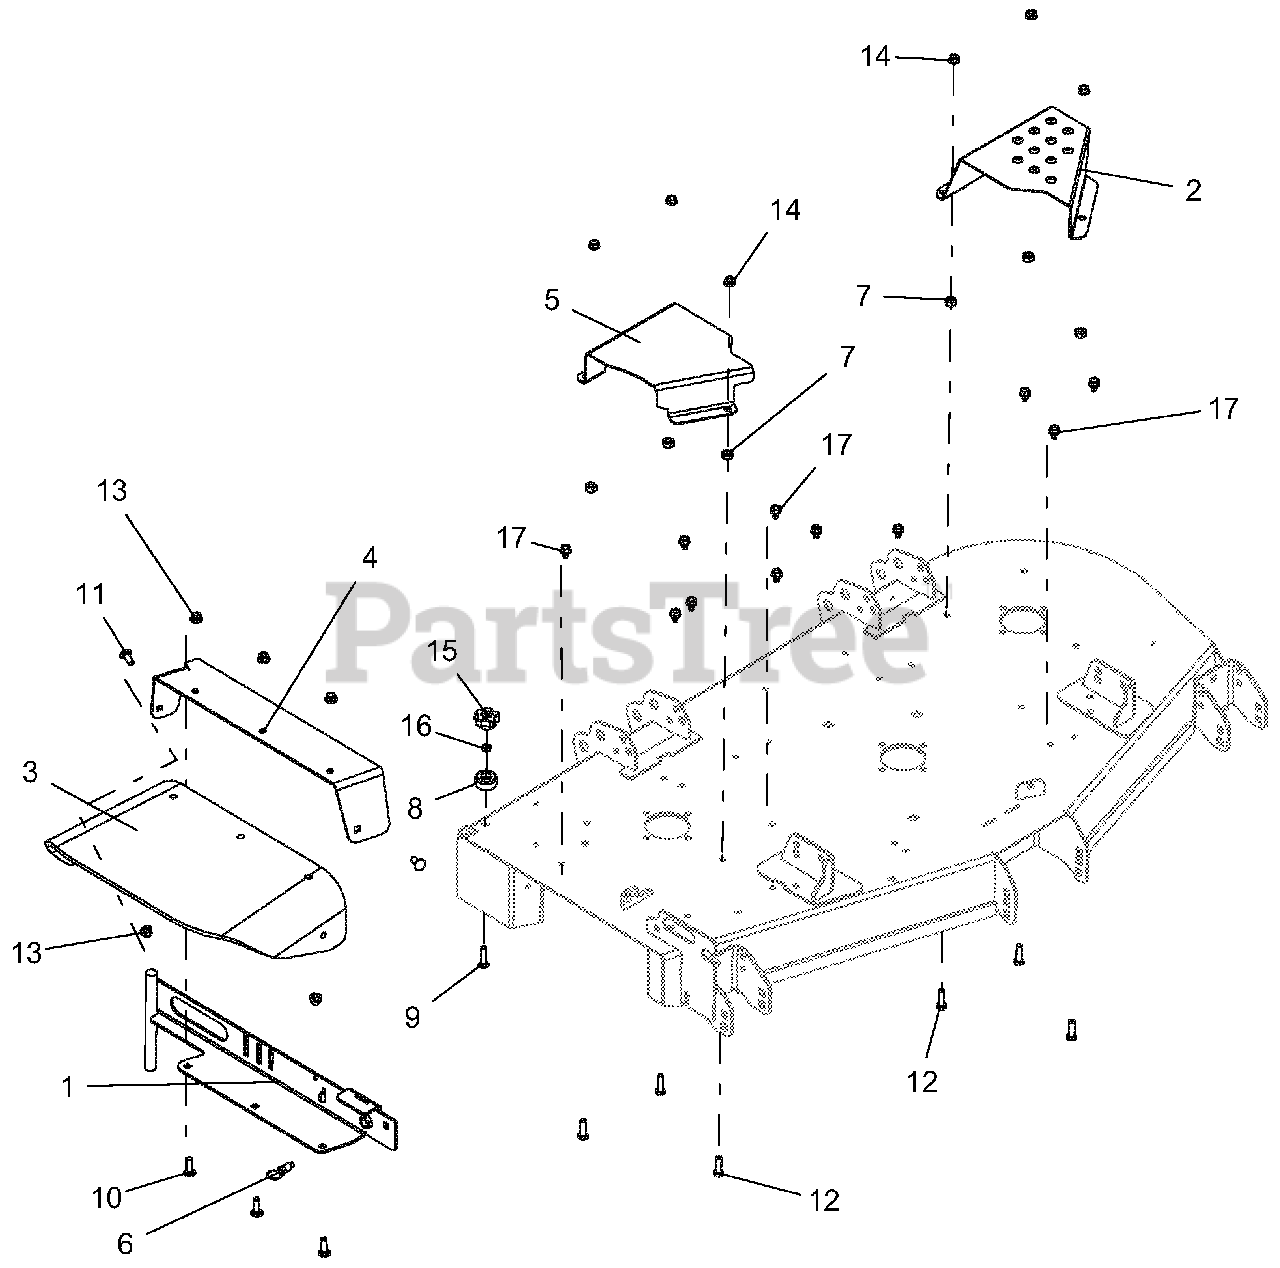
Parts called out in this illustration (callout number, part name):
1	WLDMT, 52"-60" DISCH CHUTE MTG-RED
2	GUARD, 44-52" LH DECK BELT-BLACK
3	CHUTE, RUBBER DISCHARGE
4	KIT, PT DISCH CHUTE SUPT W/SAFETY DECALS-RED
5	GUARD, 48"-52" RH DECK BELT-BLACK
6	PULL PIN,.50-13THDX.310 PLNGR
7	NUT-HEAVY HEX .38-16 YWZC
8	BUMPER, RECESSED 1.50 X .63 W/.31 HOLE
9	BLT-RDHDSQNK .31-18X1.50 G5 YWZC
10	BLT-RDHDSQNK .38-16X1.25 G5 YWZC
11	BLT-RDHDSQNK .38-16X1.00 G5 YWZC
12	BLT-HEX .38-16X1.25 GR5 YWZC
13	NUT-LK-NYL-FLG .38-16 YWZC
14	@NUT-SPNLK-FLG .375-16 YWZC
15	KNOB, CLAMPING
16	NUT-LK-CTR .31-18 YWZC
17	SCR-TAP .38-16X.50 HWH TR YWZ
